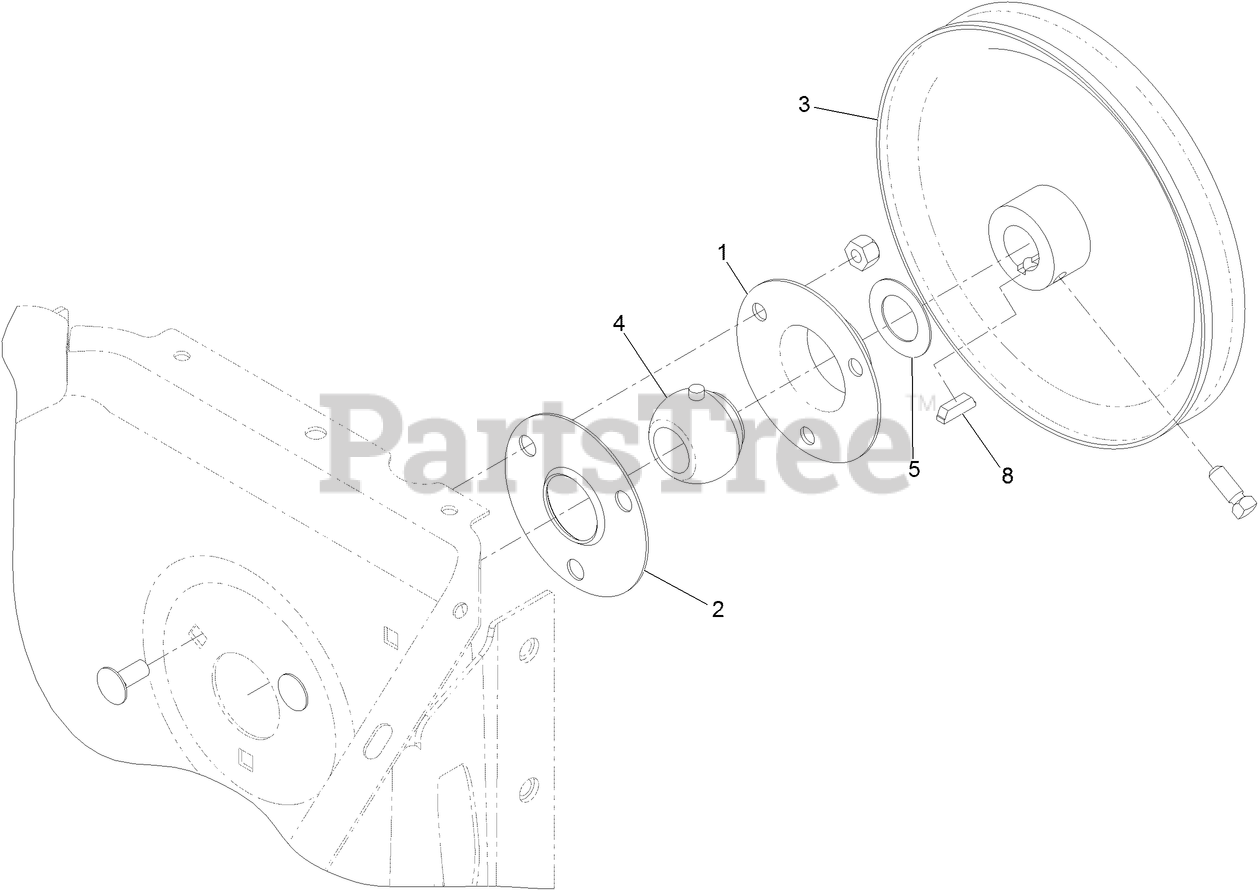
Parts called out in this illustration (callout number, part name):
1	FLANGE-CUP, BEARING
2	FLANGE-CUP, BEARING
3	PULLEY-IMPELLER
4	BEARING-BALL
5	WASHER-THRUST
8	KEY-WOODRUFF
